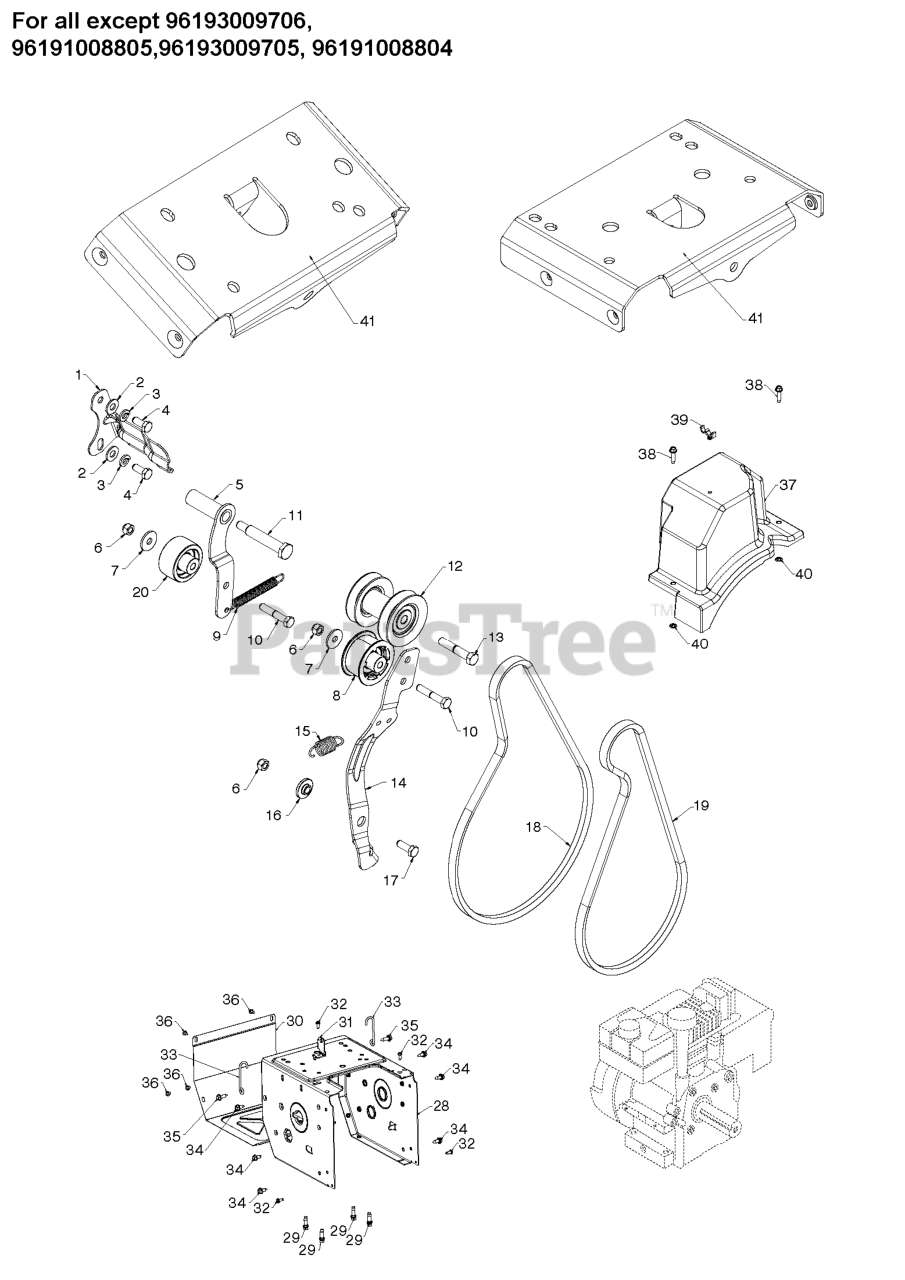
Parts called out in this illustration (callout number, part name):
1	BRACKET.BELT.KEEPER.004.BZP
1	BELT KEEPER BRACKET
2	WASHER M
3	WASHER.LOCK.HVY.HLCL.SPR.5/16
4	SCREW 5/16-24 X .75 GR5
5	ARM IDLER DRIVE WELDMENT_HOT
6	NUT.71038.31-18.HEX.NYLOCK
7	STEEL WASHER
8	PULLEY,IDLER,2.00 W SPA
9	SPRING RETURN IDLER ARM
10	BOLT, HEX 5/16-18X1-3/4
11	BOLT 5/16-24X2.25 HEX HEAD SHO
12	PULLEY.ASM.IMPELLER/DRIVE
13	BOLT.BLADE
13	BOLT.HD.HEAD.3/8-24X2.50 (2 2)
13	BOLT.ENGINE.PULLEY
14	ARM.IDLER.AUTO-PH.676
14	ARM.IDLER.SNOW.BLACK
14	BRACKET ARM.IDLER.IMPELLER ARM
15	SPRING RETURN, IDLER ARM, IMPE
15	BUSHING.BRAKE.ARM
16	BUSHING.BRAKE.ARM
17	BOLT
18	BELT.DRIVE.SNOW.DUAL
19	LOW CRANK IMPELLER BELT
20	PULLEY.IDLER.FLANG.2.O/SPACER
28	FRAME.GEAR.CASE.ORANGE
29	BOLT 3/8-16X1-1/8
30	COVER COVER.FRAME MS668 ORANGE
31	BRACKET.SHIFTER.BZP
32	SCREW 14-20 X 5/8
32	SCREW.HEX HEAD W/COLLAR 1/4-20
33	WIREFORM.SUPPORT.CABLE
34	BOLT.HEX.HD.WASHER.5/16-18X.75
35	SCREW HEX_SERR_HD_5_16-18X1.0
36	SCREW HEXAGON HEAD WITH COLLAR
36	SCREW
37	COVER COVER.BELT
37	COVER BELT ASM. LOW CRANK
38	SCREW HEX WASH THDRL BLK 1_4-
40	PALNUT 1/4
41	BRACKET.FRAME.SUPPORT.BLACK
